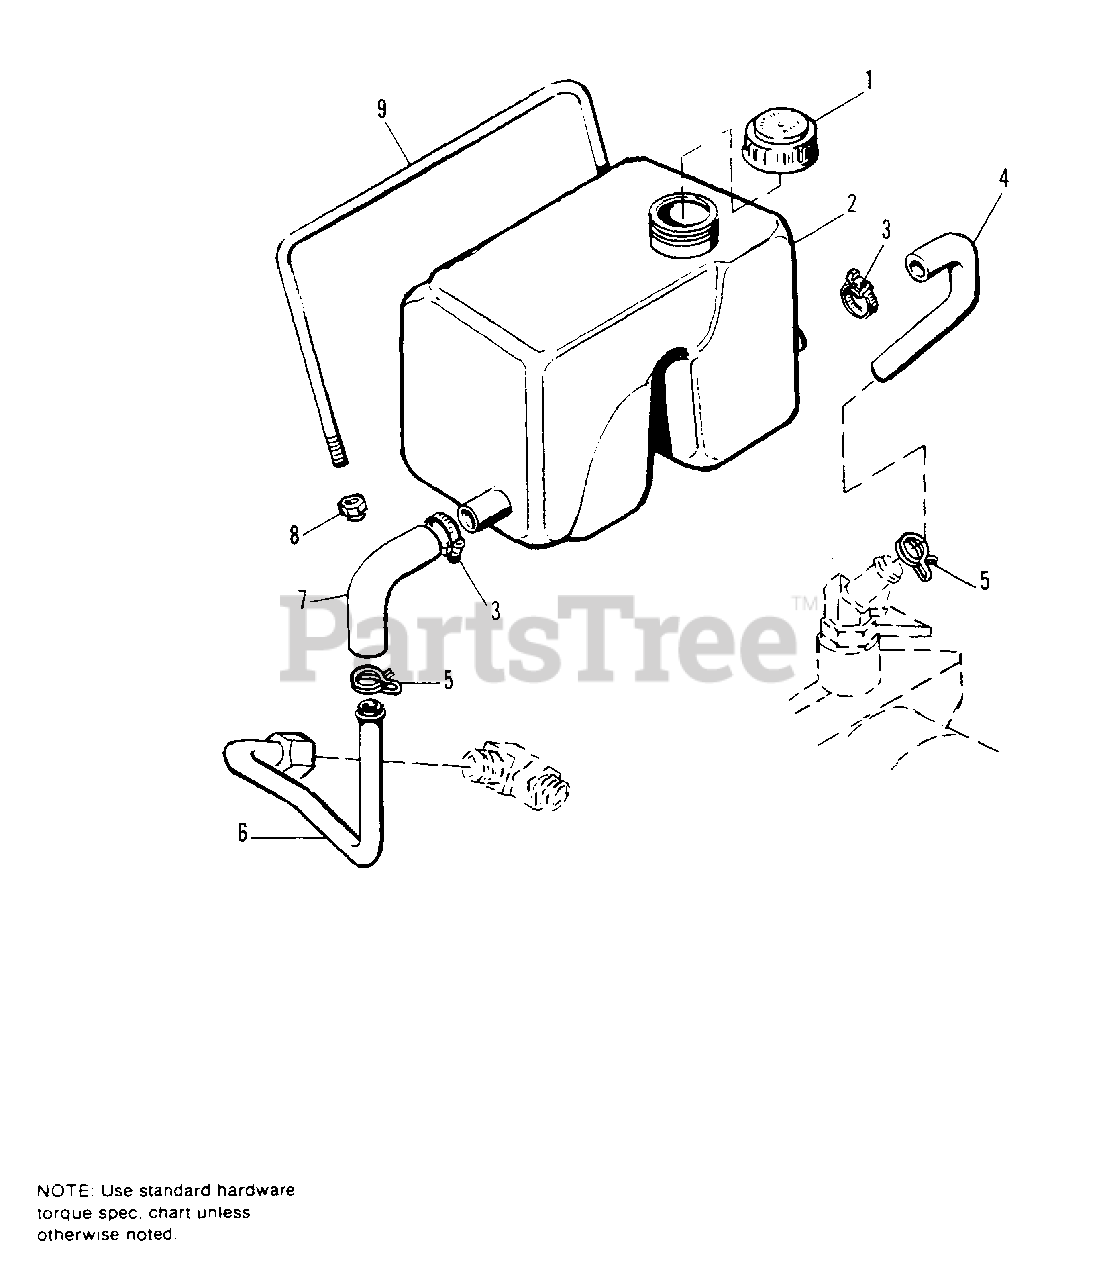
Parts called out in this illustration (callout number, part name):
1	CAP, Reservoir
2	RESERVOIR (1 Gal.)
3	CLAMP, Hose #10
4	HOSE, Hydraulic
5	CLAMP, Hose
6	LINE, Hydraulic, Steel
7	HOSE, Hydraulic
8	NUT, Hex, 1/4-20
9	ROD, Reservoir Mtg.
